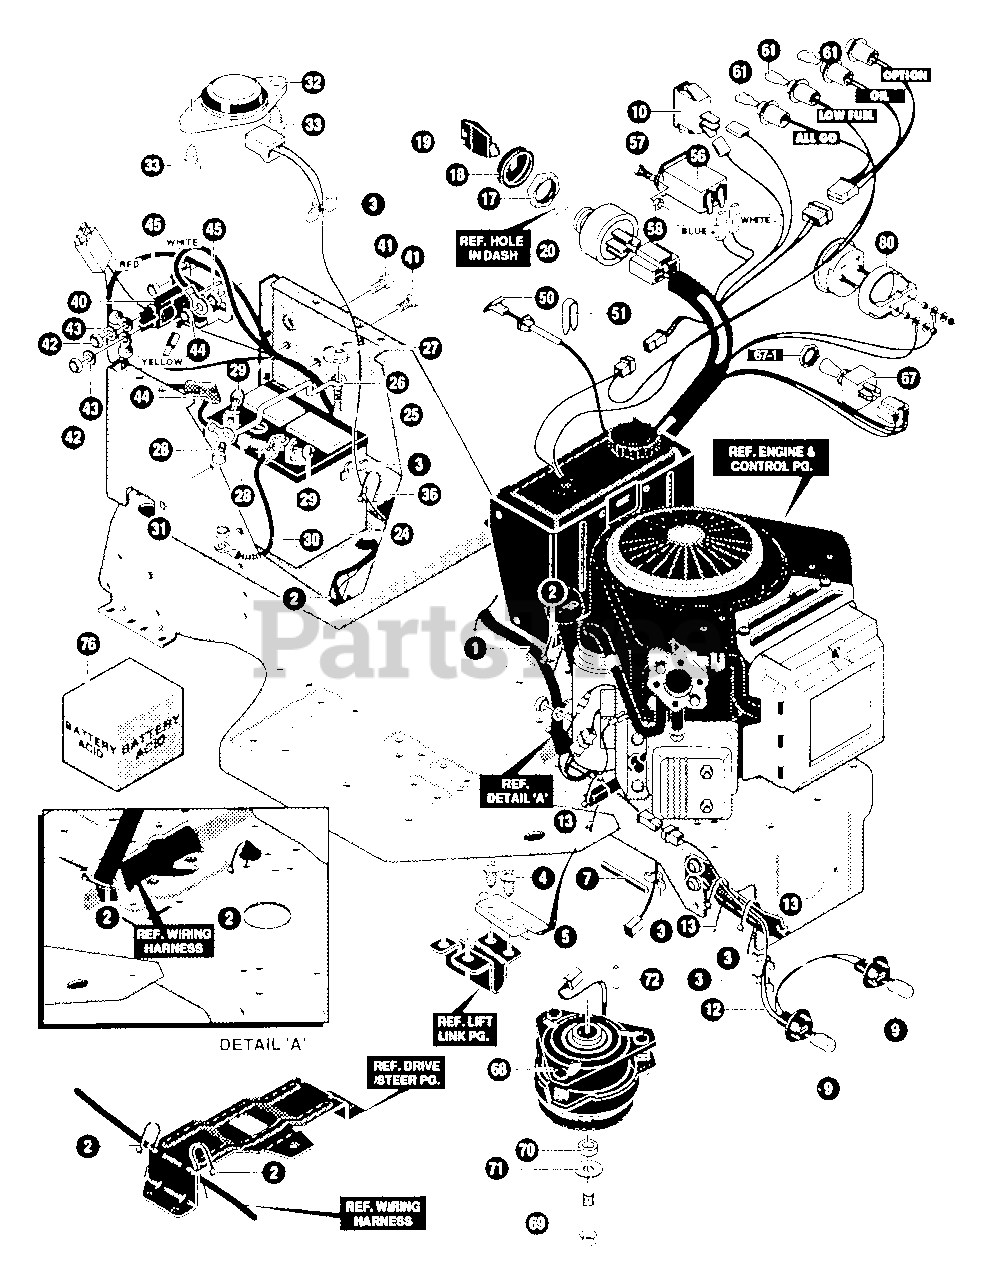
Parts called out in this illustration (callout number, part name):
1	HARNESS,WIRING EURO VG/TW E/C AMP
2	TIE, CABLE BLACK NYLON 5.62L
3	PRESS CLIP, 1.380LG .255ID
4	SCREW, #12 X .50 PHPNHTAP BLK
5	SWITCH,SCR MNT DP NC NO BLK
7	EDGING,WIDE BLK
9	BULB, HEADLAMP
10	LIGHT SWITCH ON/OFF PANEL MNT
12	ASSY,LIGHT WIRE-1/4 TURN
13	TIE, CABLE BLACK NYLON 5.62L
17	NUT, 5/8-8ACME DELTA FOR BOOT
18	BOOT, IGN SWITCH
19	KEY,IGNITION GENERIC DELTA
20	SWITCH-IGN (AFTER FIRE) 3 POSN
24	BATTERY, 12V
25	ROD, BATTERY
26	ROD, BATTERY TOP .209DIA
27	NUT, WING 1/4-20 NYLON
28	SCREW, 1/4-20X.75 HHC
29	NUT, 1/4-20 REGHEXKEPS
30	WIRE, GROUND, 12.5"
31	NUT, 5/16-18 HEXKEPS
32	SWITCH, SEAT
33	SCREW, 1/4-20X.38PHPNHMA
36	TIE, CABLE BLACK NYLON 5.62L
40	SOLENOID STARTER - ISOLATED
41	SCREW, 1/4-20X.75 HXSEMMA
42	NUT, 5/16-24 REGHEX
43	WASHER, EXLK .320X.61X.03
44	NUT, 1/4-20 REGHEXKEPS
45	NUT, 1/4-20 REGHEXCTRLK
46	TIE CABLE BLACK NYLON 5.62L
50	CHOKE CONT BS TWIN ERO LONG
51	CLIP,CHOKE CONTROL
56	MINIATURE HOUR METER 4-40V DC
57	SCREW, #6-32X.50 PHPNMA CRSS
58	NUT, #6-32 HEXKEPS
61	BULB, INDICATOR
67	SWITCH,ELEC/GLUT ACTUATOR EURO
68	CLUTCH, EL 12/18HP REG CHARGER
69	SCREW, 7/16-20X5.50 HHCGR5BLPH
70	BRING, FL .510IDX.100DX.56L
71	WASHER, REGSPTLK .459X.78X.12
72	KEY, SQUARE .250SQX2.12LG
76	BATTERY ACID PACK, 80 OZ
80	AMMETER ASSY
